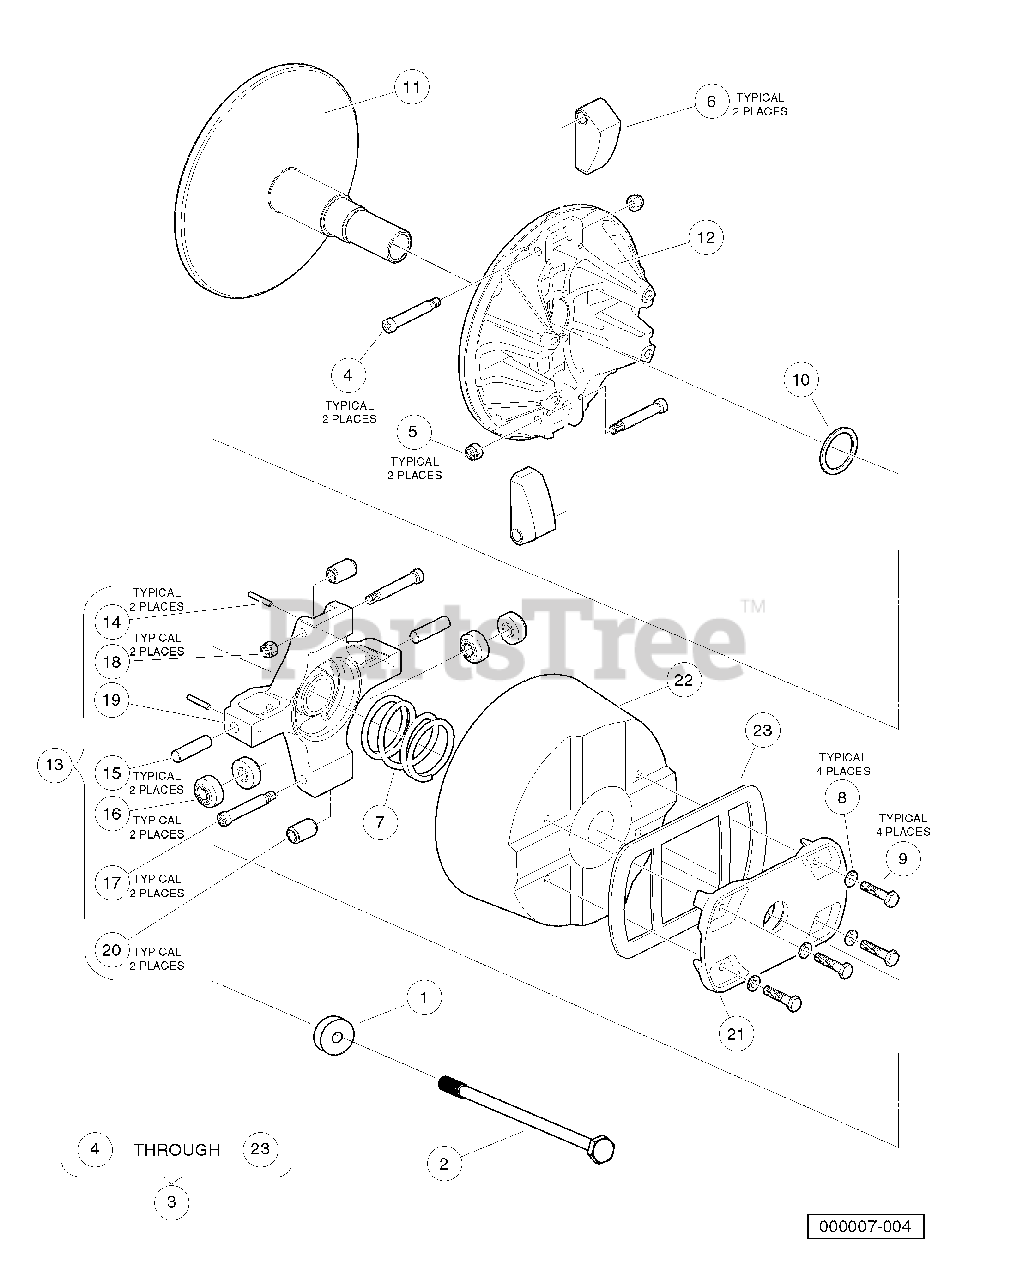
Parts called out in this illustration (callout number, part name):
1	Washer, Stepped
2	Bolt, M10 X 1.5 X 160
3	Clutch, 4x4, Diesel, W/cover
4	Screw, Shlder Hex, .312 X 1.75
5	Nut, Lock Hex, 1/14-20, Flexlc
6	Sub Assy, Wt Clutch, Diesel
7	Spring, Compression, Primary
8	Washer, Lock, H-Spring, 1/4
9	Screw, Cap, Hex Hd, 1/4 X 1.25
10	Shim, 1.63 X 1.33
11	Subassembly, Drive Clutch
12	Subassembly, Moveable, Drive Clutch
13	Subassembly, Spider Utility, Diesel
14	Pin, Spring Slotted,1.25 X 1.0
15	Pin, Dowel, .375 X 1.50
16	Roller, Torque, Diesel
17	Screw, Shlder Hex, .312 X 1.75
18	Nut, Lock Hex, 1/14-20, Flexlc
19	Spider, Drive Clutch
20	Sub Assy, Roller Weight
21	Cover, Drive Clutch
22	Cover, Clutch, 4x4
23	Gasket, Cover, Clutch, 4x4
